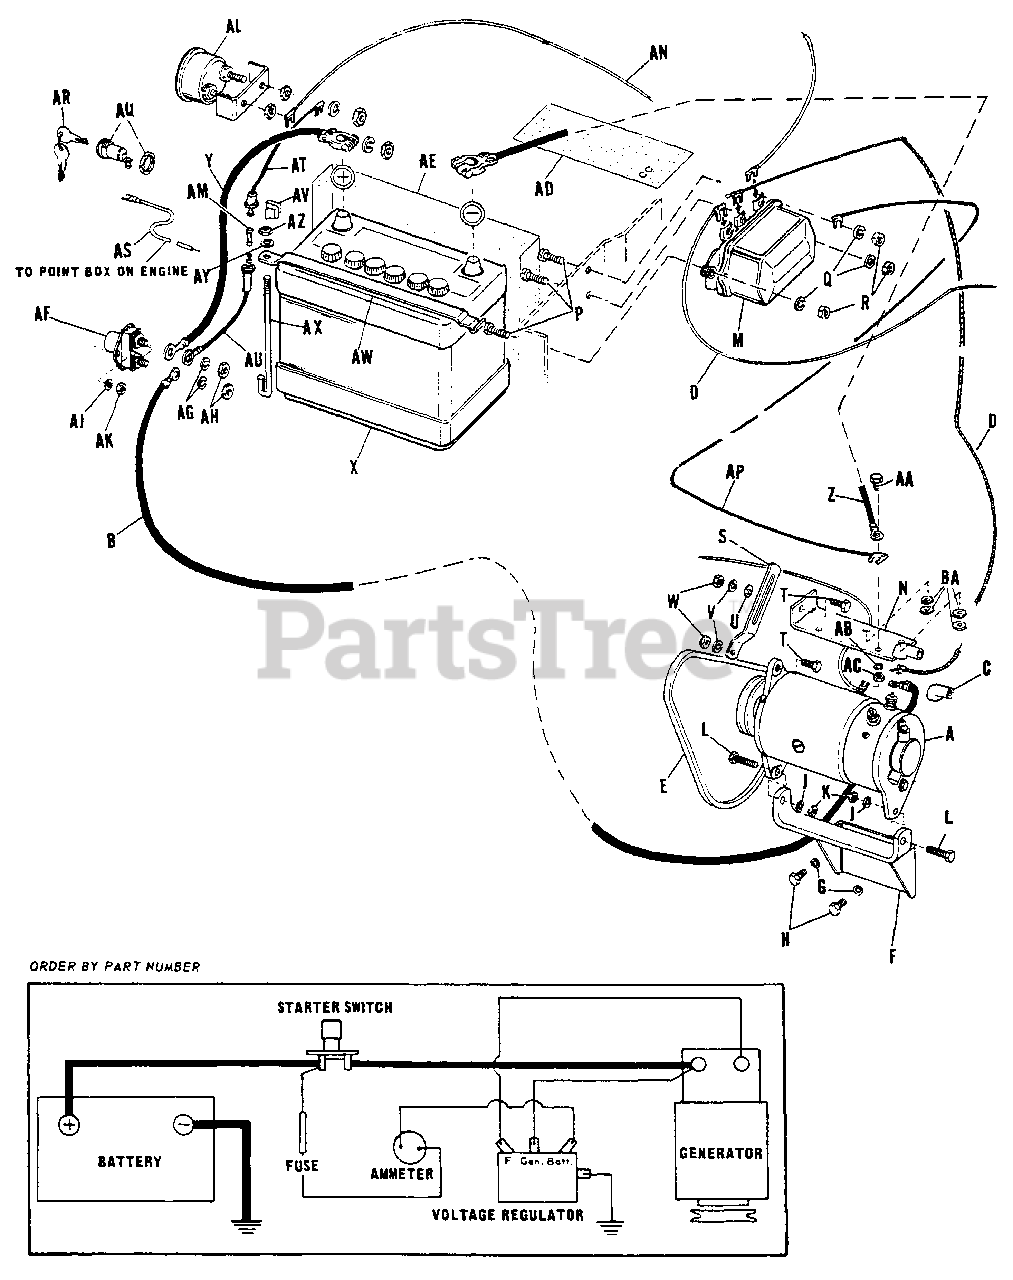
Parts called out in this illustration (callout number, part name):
A	Motor-Generator
B	Cable, Generator, Start
C	Terminal Cover
D	Wire, Reg. Gen.
E	"V"-Belt-(157524 on 399 & 400)
F	Support Assembly
G	Lock Washer, 5/16"
H	Hex Capscrew, 5/16"-18 x 3/4" lg.
J	Lock Washer, 5/16"
K	Hex Nut, Full, 5/16"-18
L	Hex Capscrew, 5/16"-18 x 1-1/4"
M	Voltage Regulator
P	Hex Capscrew, 1/4"-20 x 3/4" lg.
Q	Lock Washer, 1/4"
R	Hex Nut, Full, 1/4"-20
S	Belt Tightener
T	Hex Capscrew, 5/16"-18 x 3/4" lg.
U	Plain Washer, 5/16"
V	Lock Washer, 5/16"
W	Hex Nut, Full, 5/16"-18
X	Battery
Y	Cable (Battery to Starter)
Z	Cable (Battery to Ground)
AA	Hex Capscrew, 1/4"-20 x 5/8" lg.
AB	Lock Washer, 1/4"
AC	Hex Nut, Full, 1/4"-20
AD	Battery Insulation
AE	Fuel Tank Insulation
AF	Starter Switch
AG	Lock Washer, 3/8"
AH	Hex Nut, Full
AJ	Lock Washer, 1/4"
AK	Hex Nut, Full, 1/4"-20
AL	Ammeter
AM	Fuse 20 AMP.
AN	Wire (Ammeter to Regulator)
AP	Wire (Ground to Ground)
AQ	Ignition Switch
AS	Wire (Switch to Engine)
AT	Wire (Fuse to Ammeter)
AU	Wire (Fuse to Starter)
AV	Clip Fuse
AW	Bracket Battery
AY	Lock & Washer 1/4"
AZ	Wing Nut 1/4"-20
BA	Plain Washer
BA	Battery Film
